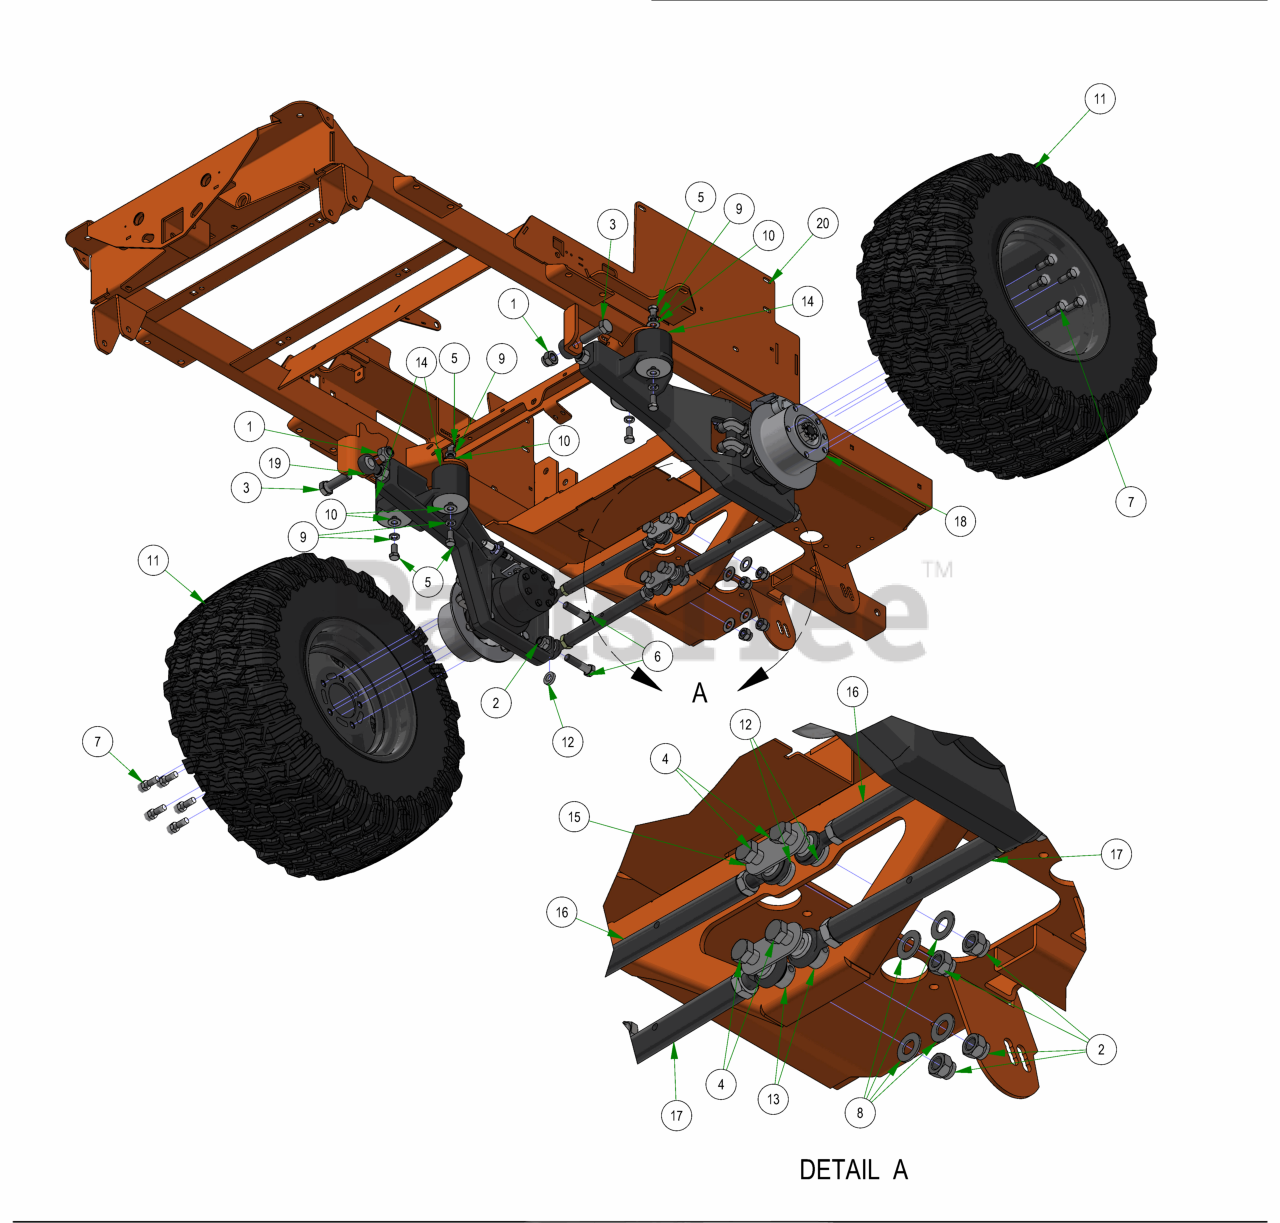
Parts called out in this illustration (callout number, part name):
1	3/4-10 NYLON INSERT LOCKNUT ZINC
2	5/8-11 NYLON INSERT LOCKNUT ZINC
3	3/4-10 X 2-1/2 HEX CAP SCREW (GR.5) ZINC
4	5/8-11 X 2-3/4 HEX CAP SCREW (GR.5) ZINC
5	1/2-13 X 1 HEX CAP SCREW (GR.5) ZINC
6	5/8-11 X 2-1/2 HEX CAP SCREW (GR.5) ZINC
7	1/2-20 x 60° Lug Bolts Zinc Grade 8
8	5/8" Flat Washer SAE Spec Grade 8
9	1/2 SPLIT LOCKWASHER (GR.8) ZINC/YELLOW
10	1/2 SAE FLAT WASHER (1-1/16" OD) GR.8 ZINC YELLOW
11	2019 Assy-26x12-12 Reaper Turf -10.5" Rim
12	Spacer 1.125OD x .625 ID x .250 Length
13	5/8 SOLID SHAFT COLLAR (W/1 SET SCREW) ZINC
14	Vibration Mount-Blue Dot
15	2019 Suspension Gusset Outlaw
16	2019 Suspension Radius Rod Assembly
17	2019 Suspension Radius Rod Assembly
18	2019 Renegade Trailing LH Arm Assy
19	2019 Renegade Trailing RH Arm Assy
20	2022 Horizontal Diesel Frame
